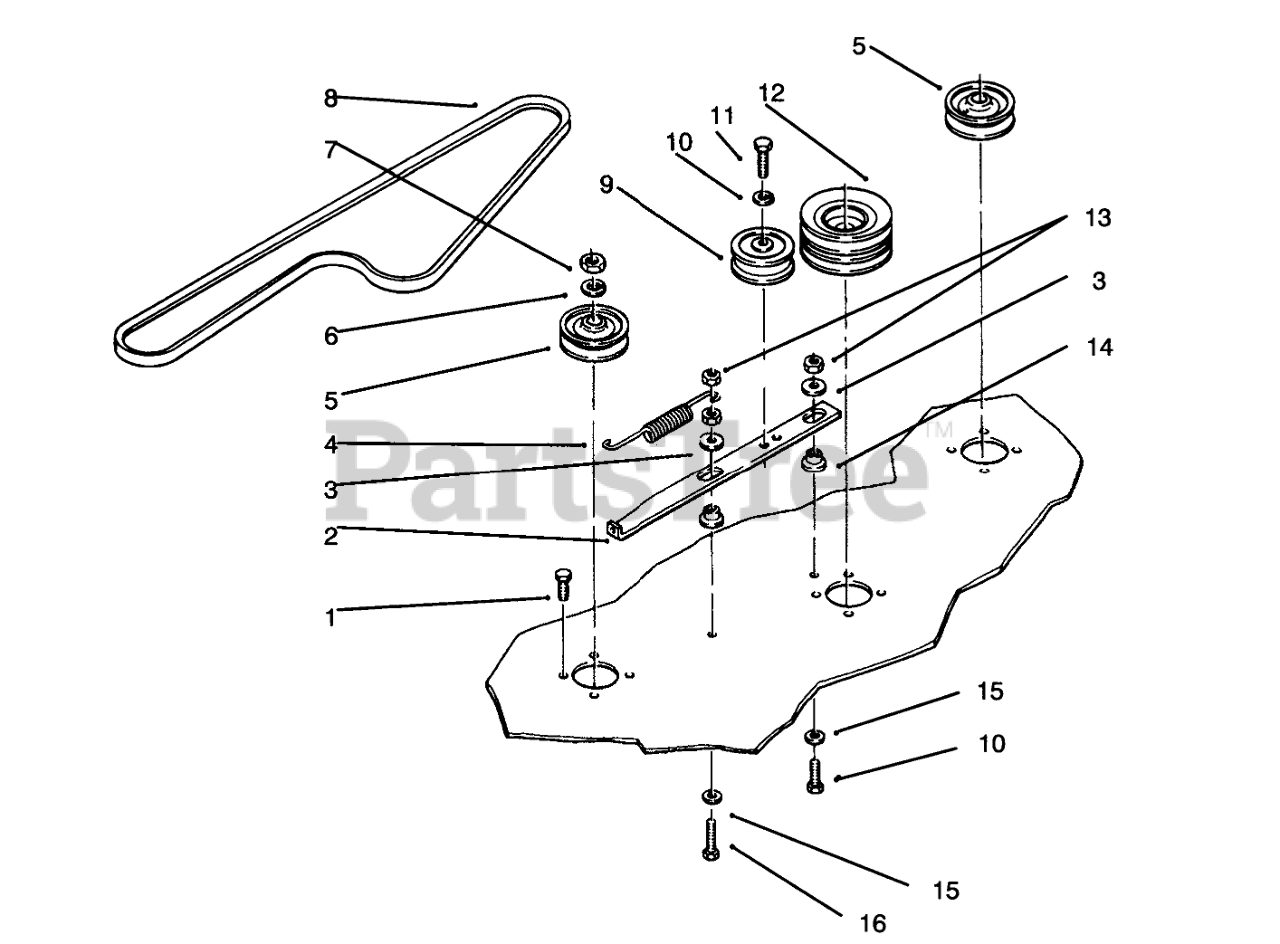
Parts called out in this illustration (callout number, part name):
1	SCREW-HH
2	BAR-IDLER SUPPORT
3	WASHER
4	SPRING-EXTENSION
5	PULLEY
6	WASHER-LOCK
7	NUT-JAM
8	V-BELT
9	PULLEY-IDLER
10	WASHER-LOCK
11	SCREW-HH
12	PULLEY CENTER
13	NUT-LOCK, NI
14	SPACER-BUSHING
15	WASHER
16	SCREW-HH
